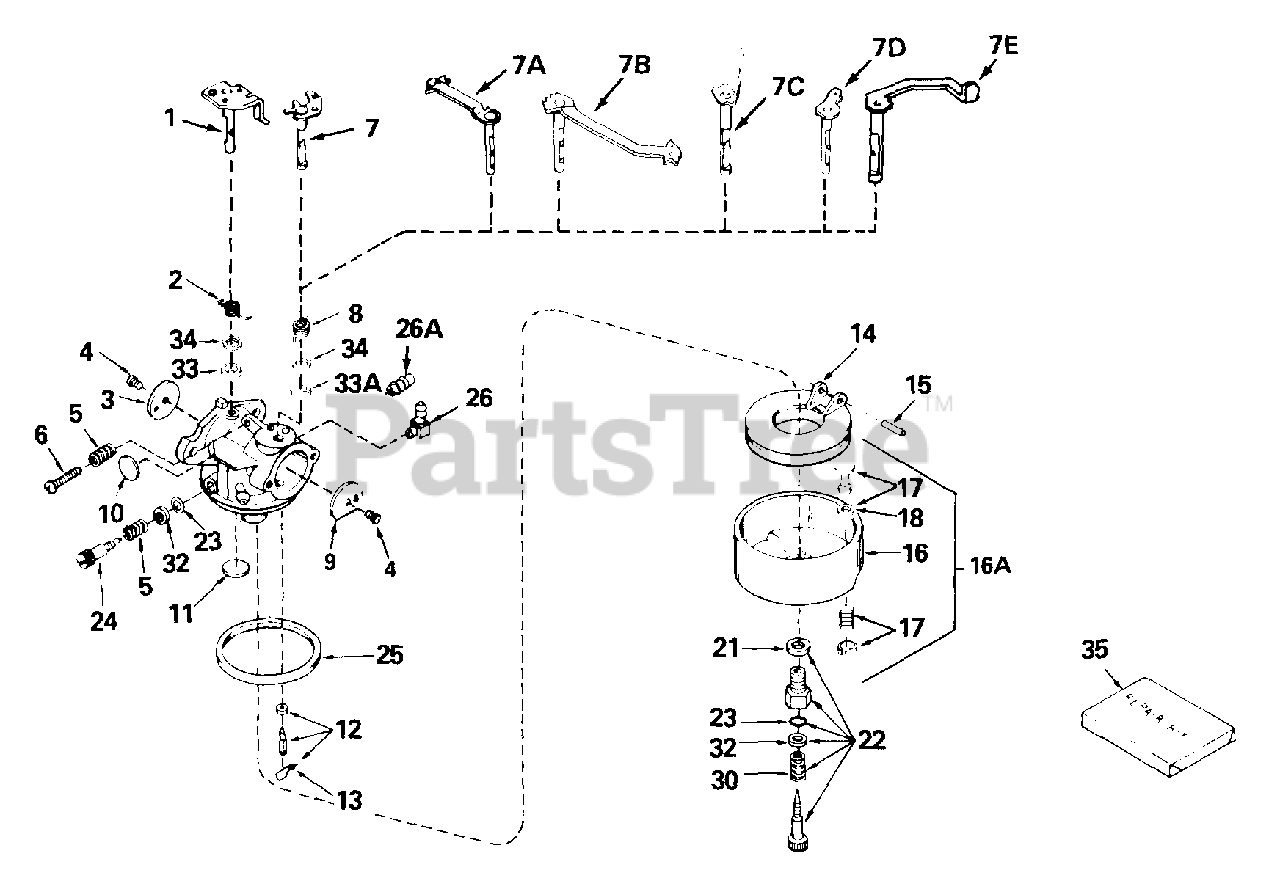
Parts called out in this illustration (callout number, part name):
1	"Shaft & Lever Assy., Throttle
2	Spring, Throttle return
3	Shutter, Throttle
4	Screw, 4-40 x 3/16
5	Spring, Idle regulating screw
6	Screw, Idle regulating
7	Shaft & Lever Assy., Choke
8	Spring, Choke return
9	Shutter, Choke
10	Plug, Welch
11	Plug, Welch
12	Inlet Needle, Seat & Clip
13	Clip, Inlet needle
14	Float, Carburetor
15	Shaft, Float
16A	Bowl & Drain Assy., Float
17	Plunger Assy., Drain
18	Gasket, Drain plunger
21	Gasket, Bowl to body
22	Adjustment Screw Assy., Main
23	"O" Ring, Adjustment screw
24	Screw, Idle adjustment
25	Gasket, Bowl-to-body
26	Fitting, Fuel inlet
30	Spring, Main adjustment screw
35	Repair Kit
